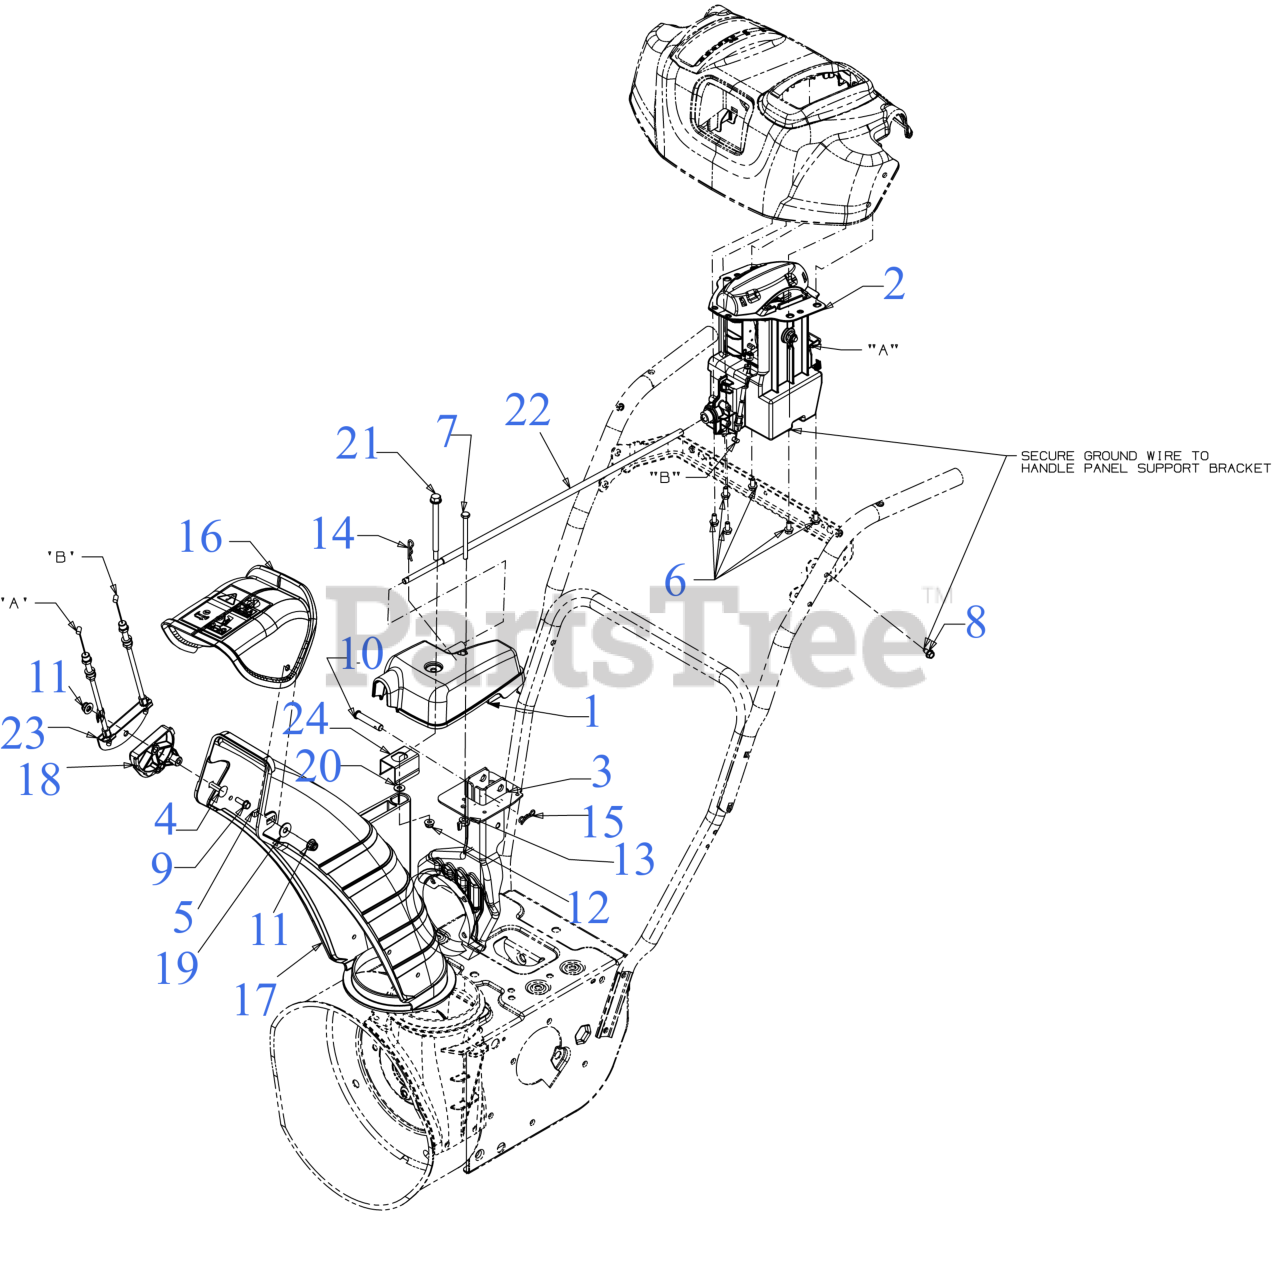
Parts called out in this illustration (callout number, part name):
1	CHUTE GEARBOX ASSEMBLY
2	CHUTE CONTROL ASSEMBLY-4-WAY ELECTRIC
3	CHUTE MAST
4	CARRIAGE BOLT 5/16-18 x 1.50
5	CARRIAGE BOLT 5/16-18 x 1
6	HEX SCREW 1/4-15 x .50
7	SCREW 1/4-20 x 3.0 GR5
8	SCREW 1/4-20 X.500
9	SCREW 1/4-15 x .750
10	CLEVIS PIN 3/8 x 1.87
11	FLANGE LOCK NUT 5/16-18
12	FLANGE LOCK NUT
13	WING NUT 1/4-20
14	INTERNAL COTTER PIN
15	BOW TIE COTTER PIN 1/4-5/16
16	UPPER REMOTE CHUTE WITH LABEL
17	LOWER CHUTE 5"
18	CABLE CHUTE GUIDE
19	FLAT WASHER
20	FLAT WASHER
21	SHOULDER SCREW
22	CHUTE CONTROL ROD .375"
24	CHUTE BRACKET
